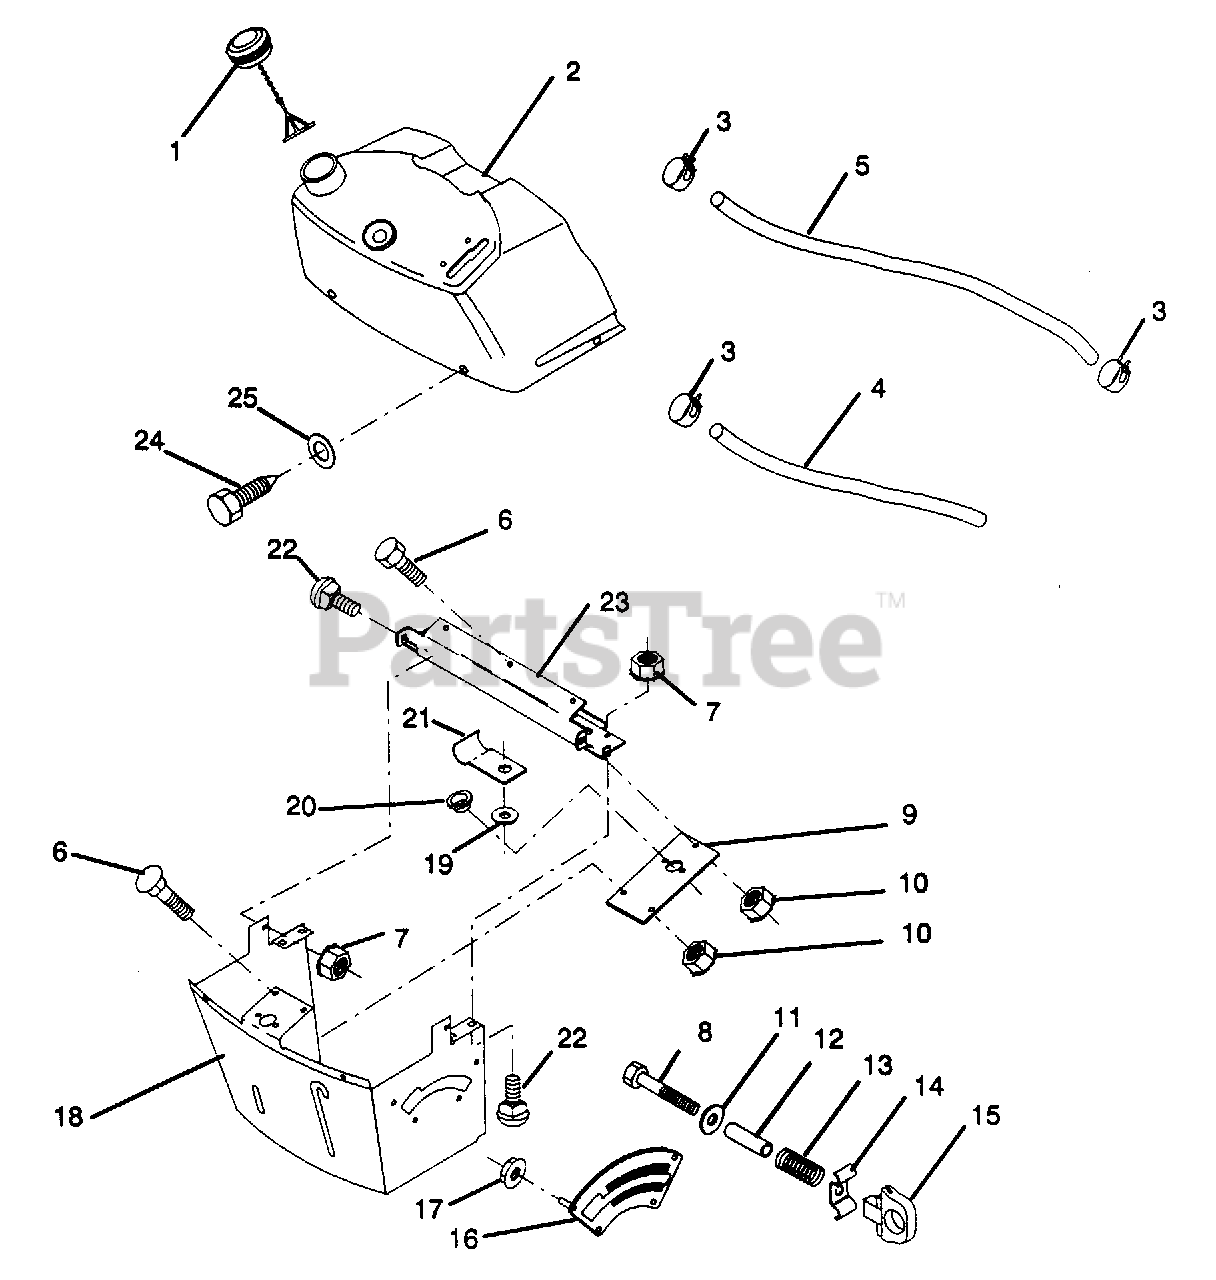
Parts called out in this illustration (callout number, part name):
1	Cap, Fuel
2	Assembly, Dash & Fuel Tank
5	Line, Fuel
6	Bolt, Hex, 1/4-20 x 3/4
7	Nut, Hex Keps 1/4-20
8	Bolt, Fin. Hex 1/4-20 x 2
9	Plate, Support
10	Nut, Lock 1/4-20
11	Washer, 11/32 x 11/16 x 16
12	Spacer, Split
13	Spring
14	Knob, Height Retainer
15	Knob, Height Stop
16	Adjustment, Quadrant Height
17	Nut, Self Thread 3/16-18
18	Support, Dash
19	Washer 9/32 x 3/4 x 16 Ga.
20	Grommet, Split
21	Clip, Fuel line
22	Bolt, Carriage 1/4-20 x 1/2 Gr.5
24	Screw, Self Tapping 1/4-20 x 1/2
25	Washer 9/32x1/2 x 16 Ga.
